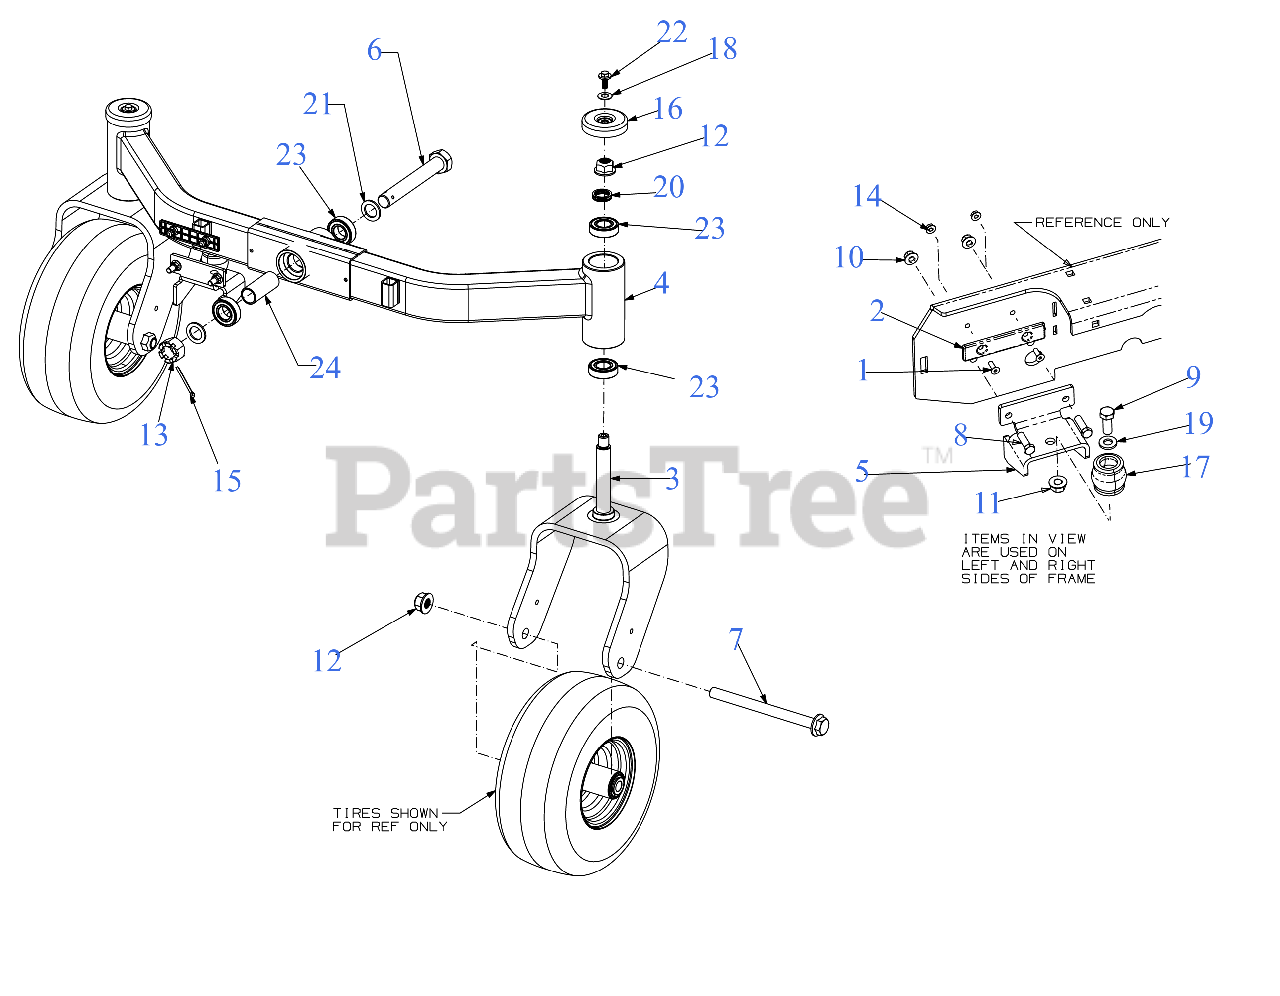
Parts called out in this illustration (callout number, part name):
1	SCREW-FLAT HEAD CA
2	PLATE-LIFT WEAR
6	HEX HEAD SCREW (1-14 x 7 GR5)
7	SCREW 3/4-16 x 9.00 GR5
8	SCREW 3/8-16 x 1.25 GR5
9	SCREW 1/2-13 x 1.25 GR5
12	FLANGE LOCK NUT 3/4-16 TOP LOCK
13	CASTLE NUT 1.0-14 GR5
14	LOCK NUT 1/4
15	COTTER PIN
16	AXLE CAP 3"
17	AXIAL BUMPER
18	BELL WASHER
19	FLAT WASHER
20	WAVE WASHER
21	FLAT WASHER 1.005 x 1.570 x 0.125
23	BALL BEARING (1.0 x 52 x 15)
24	SPACER 1.00 x 1.25 x 2.99
